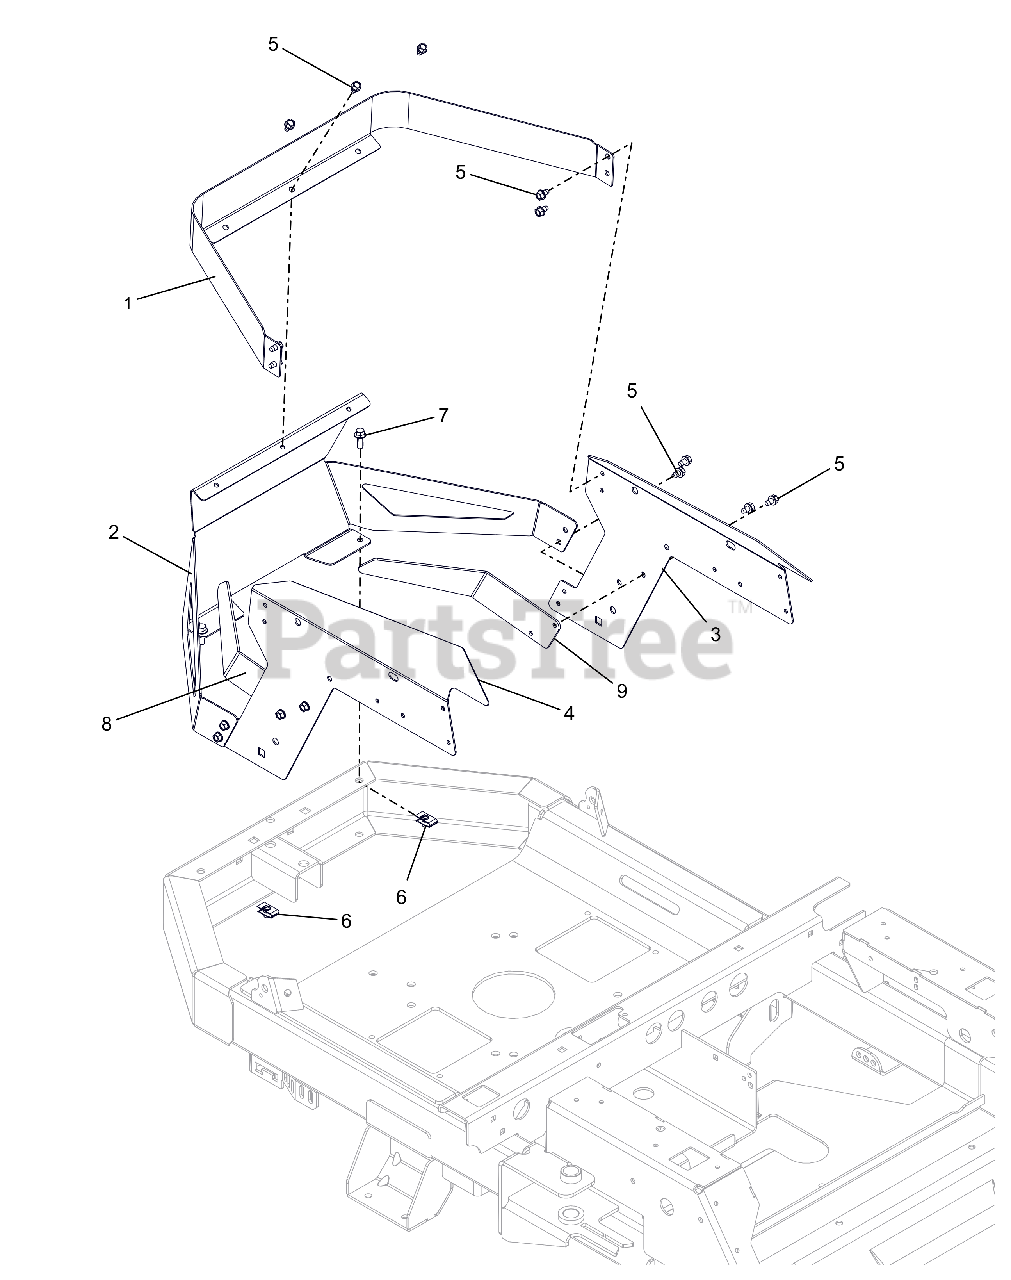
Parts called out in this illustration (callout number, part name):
1	GUARD, ENGINE -TOP TRIM
2	GUARD, ENGINE-BOTTOM BLACK
3	PANEL, LEFT REAR RENDER MOUNT
4	PANEL, RIGHT REAR FENDER MOUNT
5	SCR,TAP .25-20X.375 HWH TR ZCC
6	NUT-RTNR .25-20X.56
7	BLT,HEX-FLG .25-20X.75 G5 BFP
8	SHIELD, RH, ENGINE GUARD VALVE
9	SHIELD, LH, ENGINE GUARD VALVE
